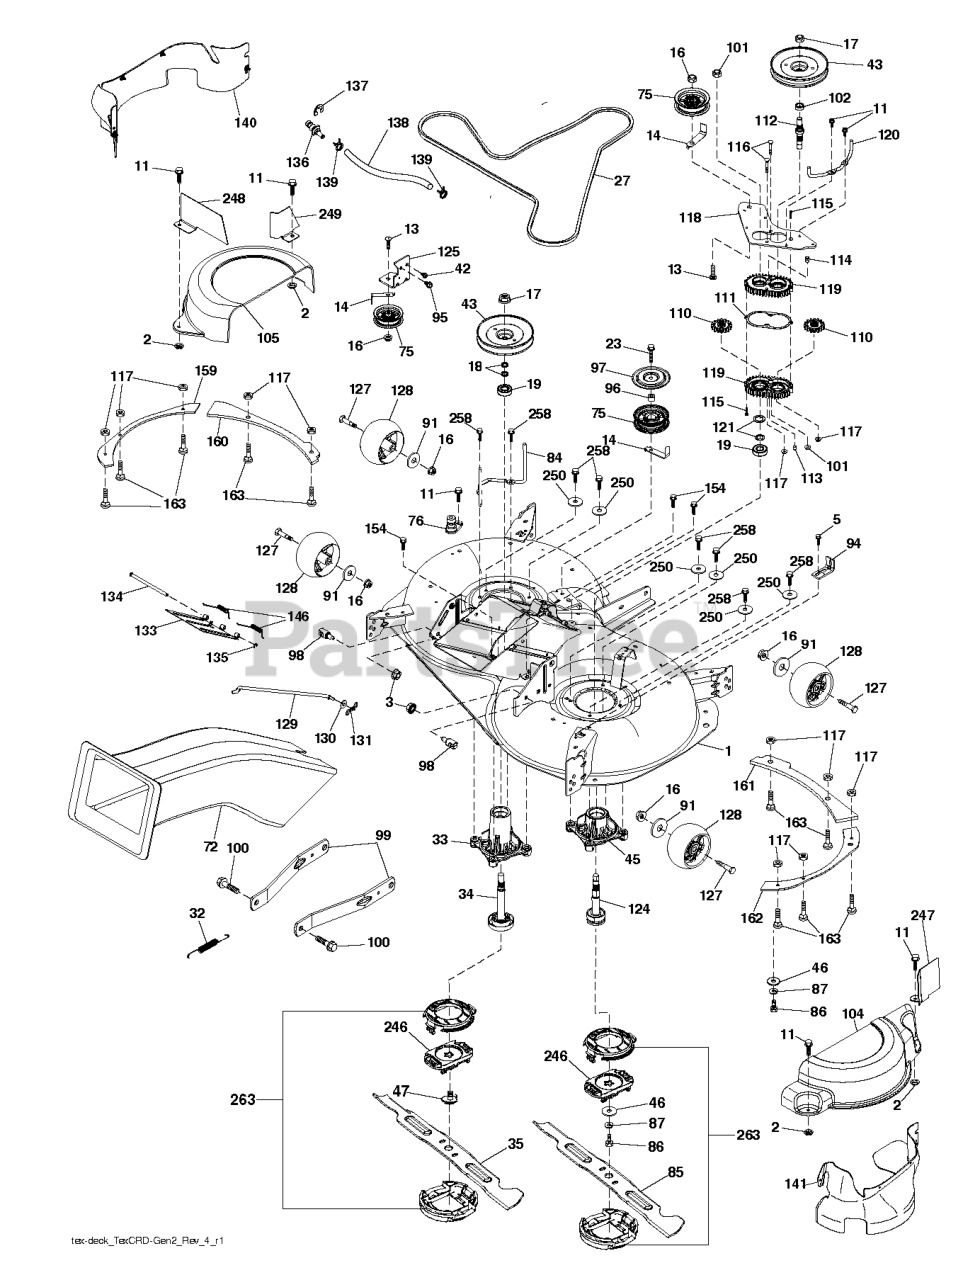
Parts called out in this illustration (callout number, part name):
1	DECK SVC 107HP.EZMUL.498
2	PALNUT 1/4
3	NUT LOCK HEX FLANGE 5/16-18
5	BOLT.5/16HEX.WHS.HD
11	SCREW.1/4-20X5/8
13	BOLT.3/8-16X1.50
14	KEEPER, BELT IDLER
16	NUT LOCK FLG 3/8-16 UNC
17	NUT.FLANGE.LOCK.TOP
18	WASHER.SPACER.MANDREL
23	SCREW LT
27	BELT BELT. ELECTRIC MOWER DRIV
32	SPRING 107CM & 97CM ELECTRIC D
33	RP.HOUSG.MAND.REV.TALL.N/GRS
34	RP.SAFT ASM.REV.TALL.N/GREASE
35	BLADE.REVLTION.107CM.LHS.PT431
42	SCREW
43	PULLEY PULLEY MANDREL 5.438 PD
45	RP HOUSING.MANDREL.REV.REVS.
46	3/8 FLAT WASHER
47	SCREW.SEMS.7/16-20X1.HEX.HEAD
72	RP.CHUTE 107/97 TEX GENII
75	FLAT IDLER PULLEY
76	1/2" BARB.DECK.WASHOUT.PORT
84	KEEPER KEEPER. LH MANDREL BELT
85	BLADE.REVLTION.107CM.RHS.PT431
86	BOLT.3/8-24X1.25GR8. LHTHRD
87	LOCKWASHER
91	WASHER
94	BRKT.CLUTCH.CABLE
95	SCREW, 3/8-16X3/4
96	SPACER
97	PROTECTOR
98	STUD.FASTNER.W/ANTI-ROTATE
99	ARM.SUSPENSION.MOWER.R
100	BOLT.SHOULDER
101	NUT.CROWNLOCK.9/16 -18.UNC
102	SPACER BEARING
104	COVER.MANDREL.107.RH.GEN.2
105	COVER.MANDREL.107.LH.GEN.2
110	CRD.SPUR.GEAR
111	GASKET GASKET GEARCASE
112	SHAFT SHAFT. CRD GEARCASE ADAP
113	PLUG PLUG OIL
114	VALVE VALVE RELIEF
115	SCREW
116	BOLT.CARIGE.SS.1/4-20X1.75GR5
117	NUT T
118	ARM ARM. CLUTCHING 107 TEX CRD
119	GEARCASE GEARCASE SUBASM
120	KEEPER KEEPER. RH MANDREL BELT
121	WASHER WASHER
124	SUB.ASM.REVERSE.THREAD.REV
125	BRACKET
127	BOLT.SHOULDER.3/8-16X3-5/8.
128	RP WHEEL. GUAGE RALLY
129	ROD ROD. SWAY CRD GEN II
130	WASHER
131	PIN.COTTER.5/16.BOW TI
133	COVER DOOR.107 CM CRD EZ MULCH
134	PIN PIN.HINGE
135	E-RING.5/16"
136	PLUG WASHOUT PORT HOOKUP
138	107.WASHOUT.PORT.HOSE (2 2)
139	HOSE.3/8.CLAMP (2 2)
140	GUARD FRENCH 107 TEX ASSEMBLY
141	GUARD SUBASM. 107 TEX GEN 2 RH
146	SPRING SPRING: EZ MULCH DOOR
154	SCREW T-30 1/4-20 X
159	REINFORCE.PLATE.LH.FT.X431
160	REINFORCE.PLATE.LHS.BOLT.431
161	REINFORCE.PLATE.RH.FRT.X431
162	REINFORCE.PLAT.RH.SD.BLT.X431
163	BOLT
246	HOLDER BLADE REVOLUTION
247	GUARD.STEEL.CRD.MANDREL.COV.FR
248	GUARD.STEEL.CRD.MANDREL.COV.FR
249	GUARD.STEEL.CRD.MANDREL.COV.FR
258	BOLT.HEX.WASHR.HED.313-18X1.19
259	CAP.REVOLUTION.UPPER
260	CAP.REVOLUTION.LOWER
